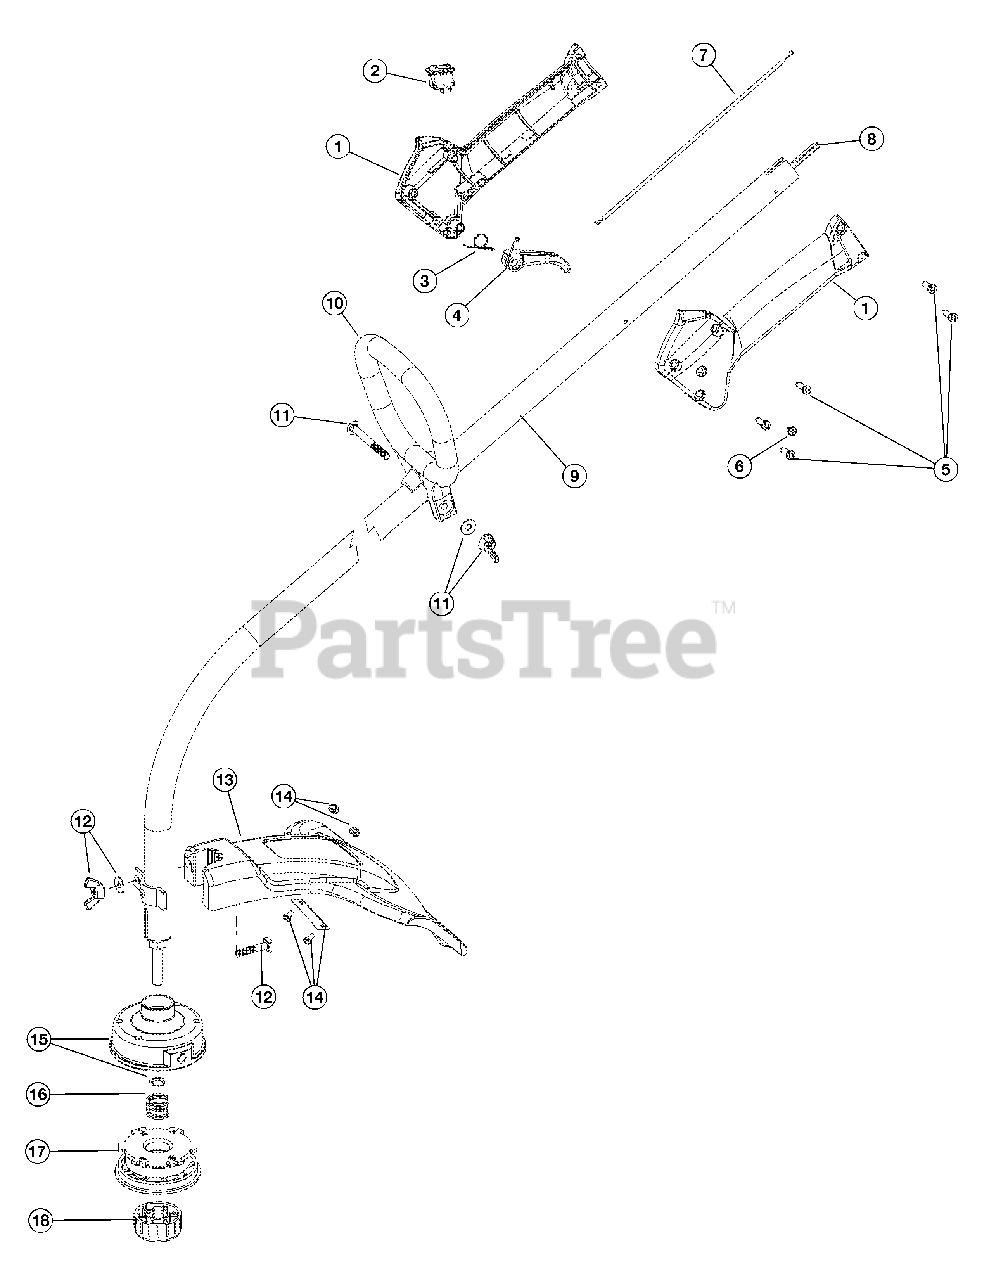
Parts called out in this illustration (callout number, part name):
1	Throttle Housing Assembly (includes 2-4)
3	Throttle Trigger Spring
4	Throttle Trigger
5	Throttle Housing Screws
6	Anti-Rotation Screw
7	Throttle Cable
8	Flexible Drive Shaft
9	Drive Shaft Housing Assembly (includes 8)
10	D-Handle Assembly (includes 11)
11	D-Handle Hardware
12	Guard Mounting Hardware
13	Guard (includes 14)
14	Blade Assembly
15	Outer Reel w/Retainer
17	Inner Reel
